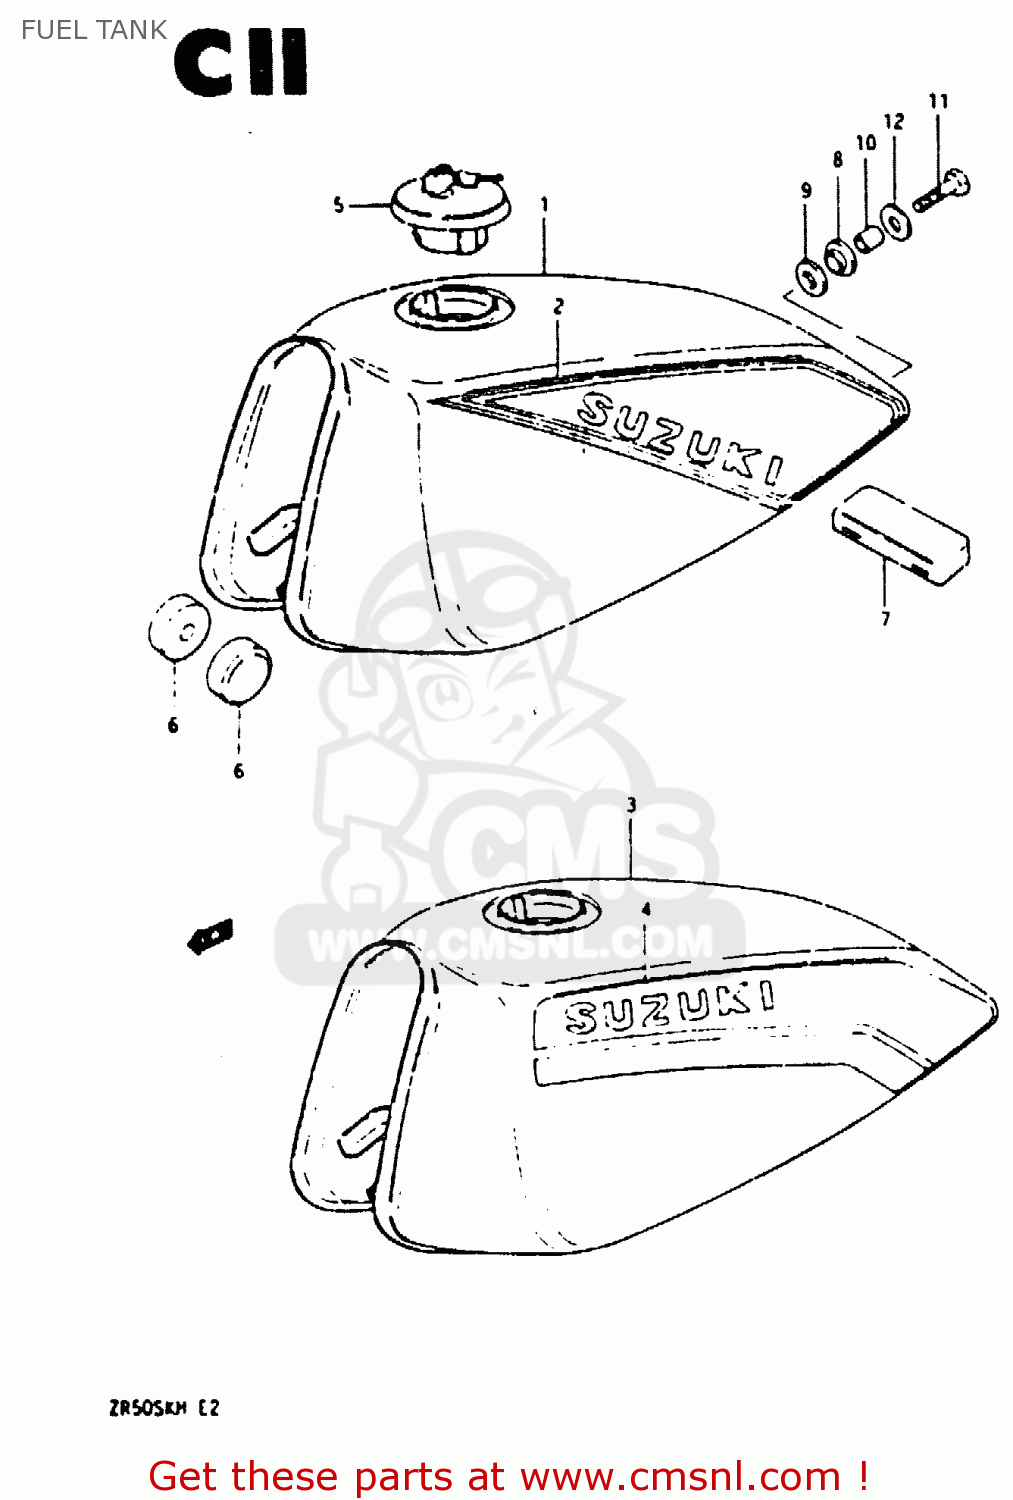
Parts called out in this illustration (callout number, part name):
1	TANK, FUEL (RED)
2	TAPE SET
3	TANK ASSY, FUEL (BLACK)
4	TAPE SET, FUEL TANK
5	CAP SET,FUEL TANK
6	CUSHION
7	CUSHION,FUEL TANK CTR
8	CUSHION
9	CUSHION
10	SPACER(8.5X12X19)
11	BOLT
12	WASHER
